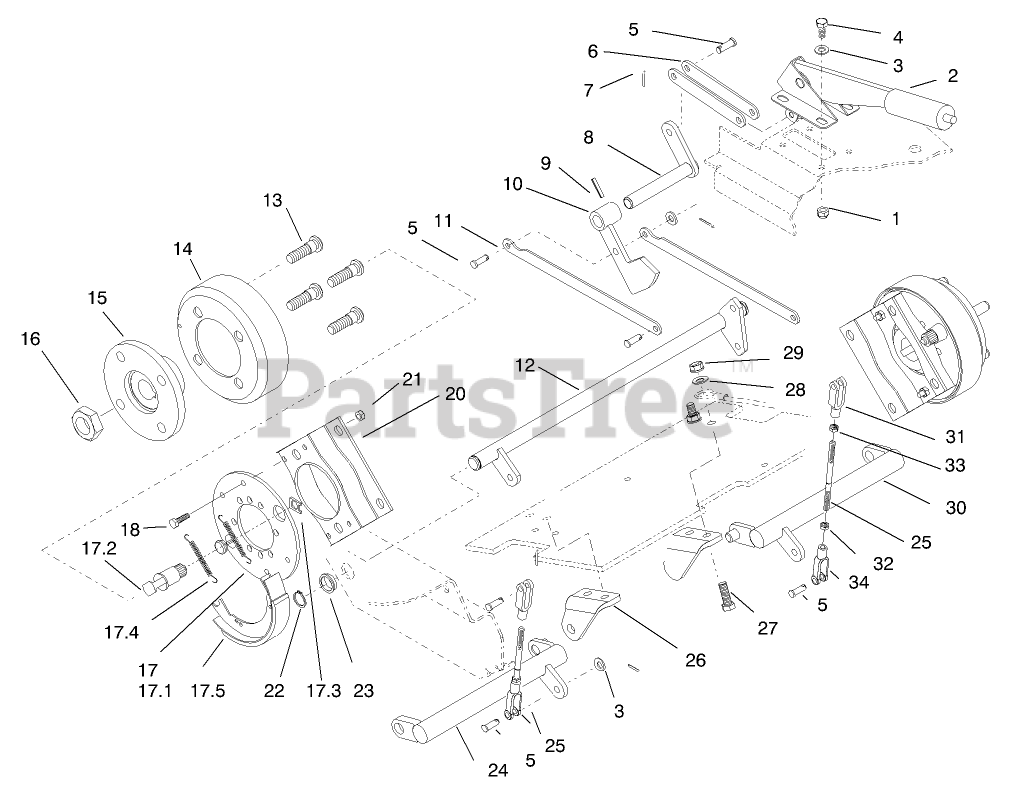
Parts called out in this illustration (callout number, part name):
1	NUT-LOCK, NI
2	LEVER-BRAKE
3	WASHER-PLAIN
4	SCREW-HH
5	PIN-CLEVIS
6	LINK-BRAKE
7	PIN-COTTER
8	TRANSFER SHAFT ASM
9	PIN-SPIRAL
10	BRAKE HUB ASM
11	LINK - CONNECT
12	TORSION SHAFT ASM
13	STUD-DRIVE
14	DRUM-BRAKE
15	Hub-Wheel
16	NUT-LOCK
17	BrakeASM
17.1	PLATE-BACKING
17.2	Cam Shaft
17.4	SPRING-RETURN
17.5	SHOE-BRAKE
18	SCREW-HH
20	Bracket-Brake
21	NUT-LOCK, NI
22	Ring-Snap
23	BUSHING
24	RH BRAKE LEVER ASM
25	ROD-BRAKE
26	MOUNT-LEVER, BRAKE, RH
27	SCREW-HH
28	WASHER-FLAT
29	NUT-LOCK, NI
30	LH BRAKE LEVER ASM
31	YOKE
32	NUT-JAM
33	NUT-JAM
34	CLEVIS-ADJUSTABLE
